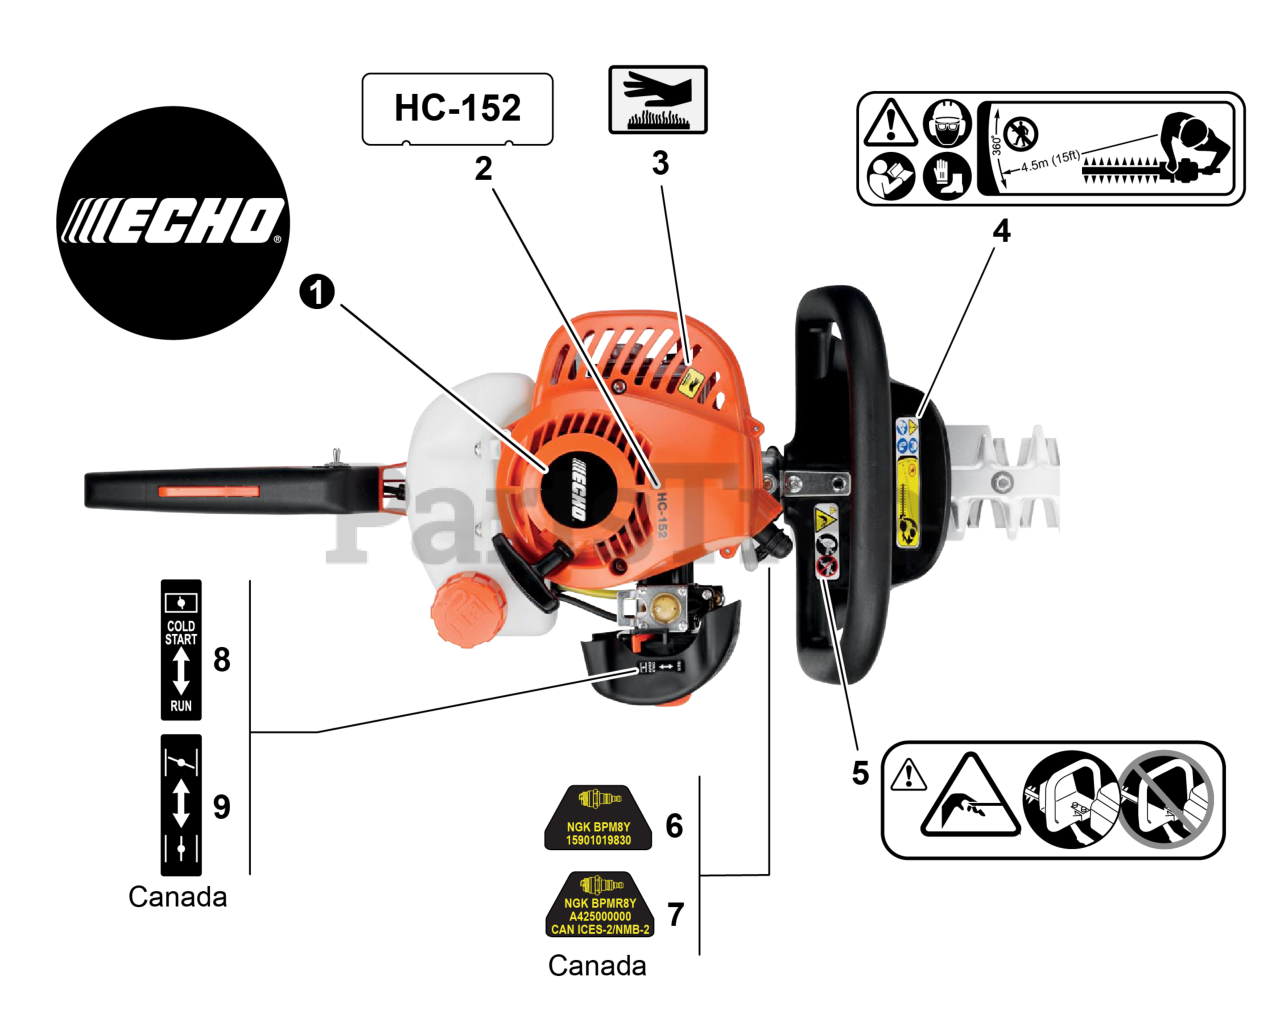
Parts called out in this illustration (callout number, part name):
1	LABEL - STARTER - ECHO
2	LABEL - MODEL HC-152
3	LABEL - CAUTION - HOT
4	LABEL - CAUTION - ISO
5	LABEL - CAUTION
6	LABEL - SPARK PLUG - BPM8Y
7	LABEL - SPARK PLUG - BPMR8Y
8	LABEL - CHOKE
9	LABEL - CHOKE
